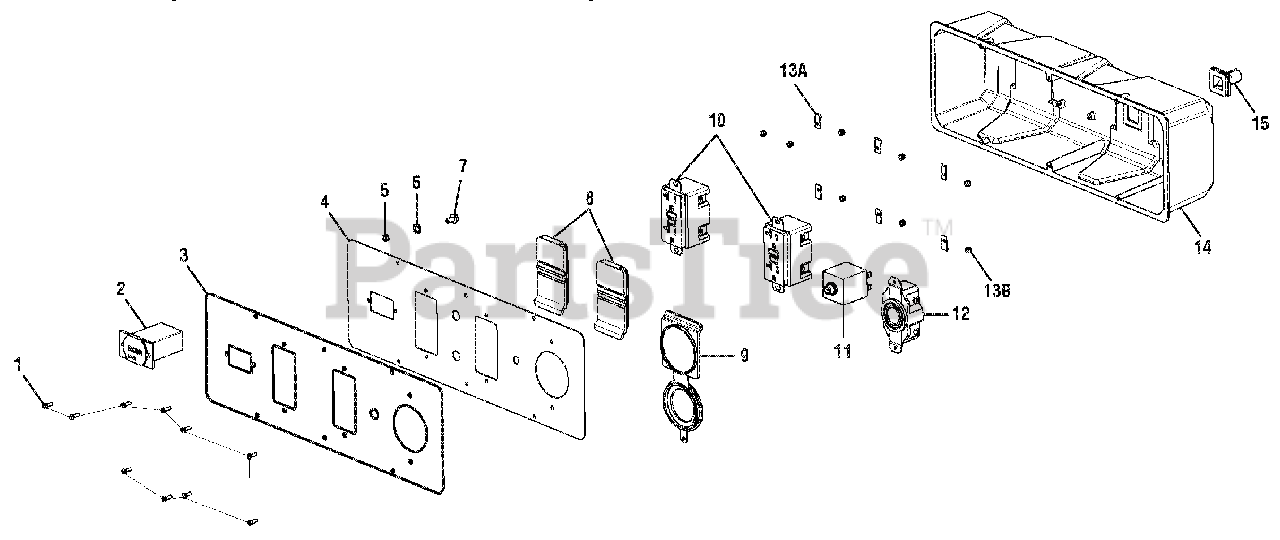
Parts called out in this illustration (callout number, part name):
1	Screw (6-20 x 3/8 in.)
2	Hour Meter (120 Volt)
3	Label (Power Outlet)
4	Front Panel
5	Lock Nut (M4)
6	Star Washer (ID6.4 x OD11 x 0.6t)
7	Bolt (M5 x 10 mm, Hex Hd.)
8	Outlet Cover (120 Volt)
9	Outlet Cover (240 Volt)
10	120 Volt Duplex Receptacle (GFCI)
11	Circuit Breaker (20 Amp)
12	Twist Lock Receptacle (120/240 Volt, 30 Amp, L14-30R)
13B	Lock Nut
14	Control Box (Back Panel)
15	Rubber Boot
